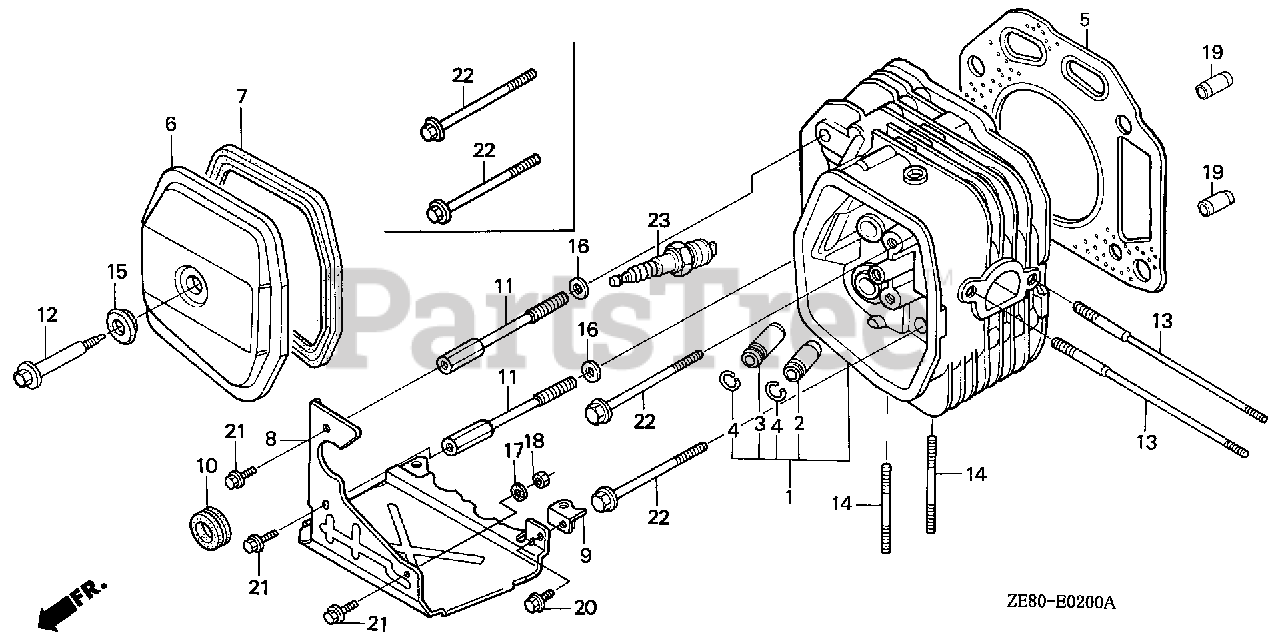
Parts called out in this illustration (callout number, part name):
1	CYLINDER HEAD
1	CYLINDER HEAD (NOT AVAILABLE)
2	GUIDE, VALVE (OVER SIZE)
3	GUIDE, EX. VALVE (OVER SIZE)
4	CLIP, VALVE GUIDE
5	GASKET, CYLINDER HEAD
6	COVER, HEAD
7	GASKET, HEAD COVER
11	BOLT, SPECIAL HEAD COVER
12	BOLT, HEAD COVER
13	BOLT, STUD (8X131.5)
13	WASHER (10.2X20)
14	BOLT, STUD (8X47)
15	WASHER, HEAD COVER
16	WASHER, SPECIAL (11X21X2.3)
19	PIN, DOWEL (12X20)
22	BOLT, FLANGE (10X80)
23	SPARK PLUG (BPR5ES) (NGK)
23	SPARK PLUG (W16EPR-U) (DENSO)
